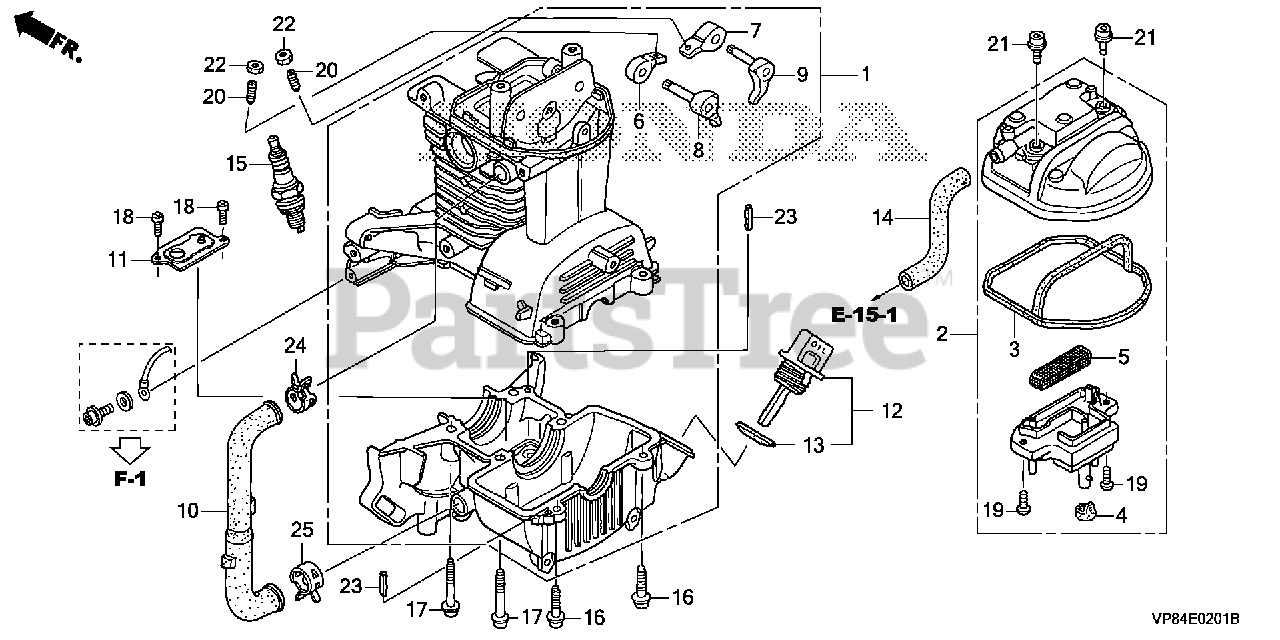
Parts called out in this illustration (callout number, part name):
1	CRANKCASE SET
2	COVER, CYLINDER HEAD
3	SEAL, HEAD COVER
4	GROMMET, HEAD COVER
5	FILTER, BREATHER
6	ARM, IN. VALVE ROCKER
7	ARM, EX. VALVE ROCKER
8	LIFTER, IN. VALVE
9	LIFTER, EX. VALVE
11	PLATE ASSY., OIL OUTLET VALVE
12	CAP ASSY., OIL FILLER
13	GASKET, OIL FILLER CAP
14	TUBE, BREATHER
15	SPARK PLUG (CMR4H) (NGK)
15	SPARK PLUG (CMR5H) (NGK)
15	SPARK PLUG (CMR6H) (NGK)
16	BOLT, SOCKET (5X20)
17	BOLT, SOCKET (5X32)
18	SCREW, PAN (4X8)
19	SCREW, PAN (4X8)
20	SCREW, TAPPET ADJUSTING
21	BOLT, SOCKET (5X12)
22	NUT, TAPPET ADJUSTING
23	PIN, SPRING (4X10)
24	CLAMP, TUBE (D12)
25	CLAMP, TUBE (D13)
